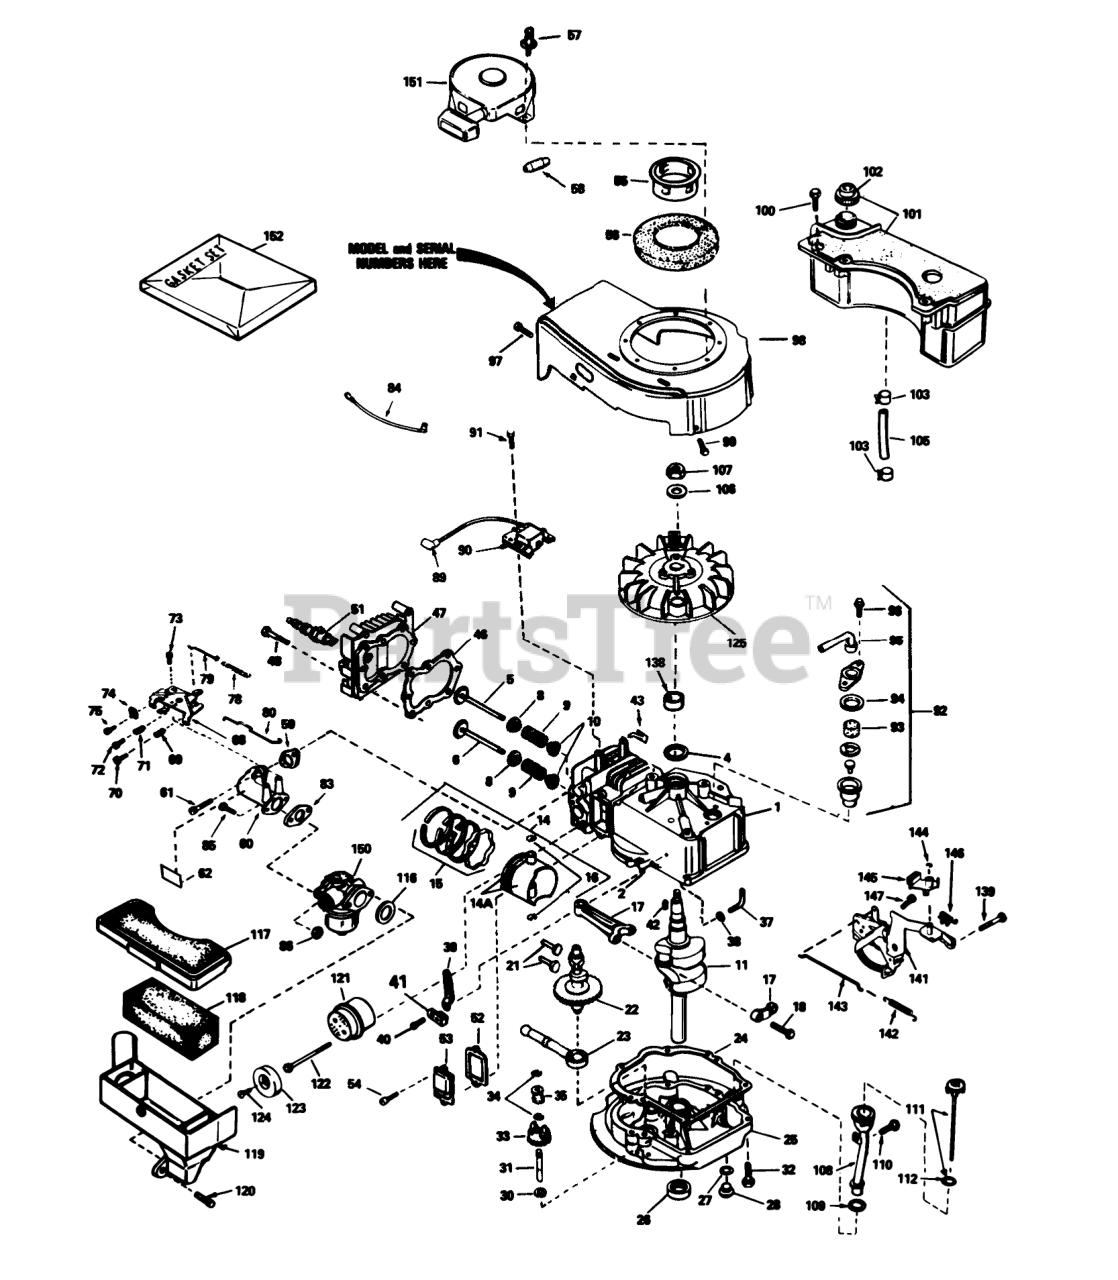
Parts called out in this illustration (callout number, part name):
1	Cylinder Assy. (Incl. #2 & 4)
2	Pin-Dowel
4	Seal-Oil
5	Valve-Intake (Std.)(Incl. #10)
5	Valve-Intake (1/32" Oversize)(Incl. #10)
6	Valve-Exhaust (Std.)(Incl. #10)
6	Valve-Exhaust (1/32" Oversize)(Incl. #10)
8	Cap-Upper Valve Spring
9	Spring-Valve
10	Cap-Valve, Spring
11	Crankshaft
14	Piston-Pin & Ring Assy. (Std.)(Incl. #14A, 15 & 16)
14	Piston-Pin & Ring Assy. (.010 Oversize)(Incl. #14A, 15 & 16)
14	Piston-Pin & Ring Assy. (.020 Oversize)(Incl. #14A, 15 & 16)
14A	Piston & Pin Assy. (Std.)(Incl. #16)
14A	Piston & Pin Assy. (.010 Oversize)(Incl. #16)
14A	Piston & Pin Assy. (.020 Oversize)(Incl. #16)
15	Piston Ring Set Std.
15	Piston Ring Set .010 O.S.
15	Piston Ring Set .020 O.S.
16	Ring-Retaining, Piston Pin
17	Rod Assy.-Connecting (Incl. #18)
18	Screw-Connecting Rod
21	Lifter-Valve
22	Camshaft(Mech.Comp. Release)
23	Oil Pump ASM
24	Gasket, Mounting
25	Flange Assy.-Mounting (Incl. #26, 27. 28 & 31)
26	Seal Oil
27	Gasket-Oil Drain
28	Plug Oil Drain
30	Washer-Flat
31	Shaft-Governor
32	Screw (1/4-20 x 1-1/4)
33	Gear Assy.-Governor (Incl. #30)
34	Ring-Retaining
35	Spool-Governor
37	Rod-Governor (Incl. #38)
38	Washer-Flat
39	Governor Lever
40	Screw
41	Clamp-Lever, Governor
42	Key-Flywheel
43	Clip-Wire
46	Gasket-Cylinder Head
47	2025A67 ADD.ASSEMBL
48	Screw (5/16-18x1-1/2)
51	Plug, Spark (Autolite 458, Champion J-19LM or equiv.)
52	Gasket-Breather
53	Cover-Valve
55	Cup-Starter
56	Screen-Starter
57	Pop Rivet (Can be purchased locally)
58	Retainer-Starter Rope
59	Gasket-Intake
60	Pipe-Intake (Incl. #59)
61	Screw (1/4-20 x 1)
62	Decal-Primer
68	Control Assy.-Remote Speed (Incl. #69-72)
69	61709/GIL1515A/95-5
70	Screw
71	Spring-Compression
72	Screw
73	Screw (10-24 x 9/16)
74	Conduit
75	Screw (10-32 x 3/8)
78	Spring Governor
79	2035A67 ADD.ASSEMBL
80	Link-Throttle
83	Gasket
84	Ground Wire
85	Screw (1/4-28 x 7/8)
86	Nut and Lock Washer (1/4-28)
89	Cover-Spark Plug
90	Lamination & Coil Assy. (Solid State)(Incl. #89)
91	Screw
92	Breather Assy. (Incl. #93-96)
93	Element-Breather
94	Gasket-Breather
95	Tube, Breaker
96	Screw (10-24 x 9/16)
97	Screw (10-24 x 9/16)
98	Housing-Blower
99	Screw (1/4-20 x 1/2)
100	Screw (10-32 x 35/64)
101	Tank Assy.-Fuel (Incl. #102)
102	Cap-Fuel
103	Clamp-Line, Fuel
105	Line-Fuel
106	Washer-Belleville
107	Nut-Flywheel
108	Tube-Oil Fill
110	Screw (10-32 x 1/2)
111	Dipstick-Oil (Incl. #112)
116	Gasket-Cleaner, Air
117	Cover Air Cleaner
118	Filter-Air Cleaner
119	Body Air cleaner
121	Muffler (Incl. #122)
123	Cover-Muffler
124	Screw
125	Flywheel
139	Screw (1/4-20 x 3/8)
141	Bracket Assy.
142	Spring-Extension
143	Link-Control
144	Ring-Retaining
145	Lever-Brake
146	Terminal
147	Screw-Hex. Hd.
150	Carburetor (Incl. #83)
151	tarter-Rewind
152	Gasket Set (Incl. Items Marked )
